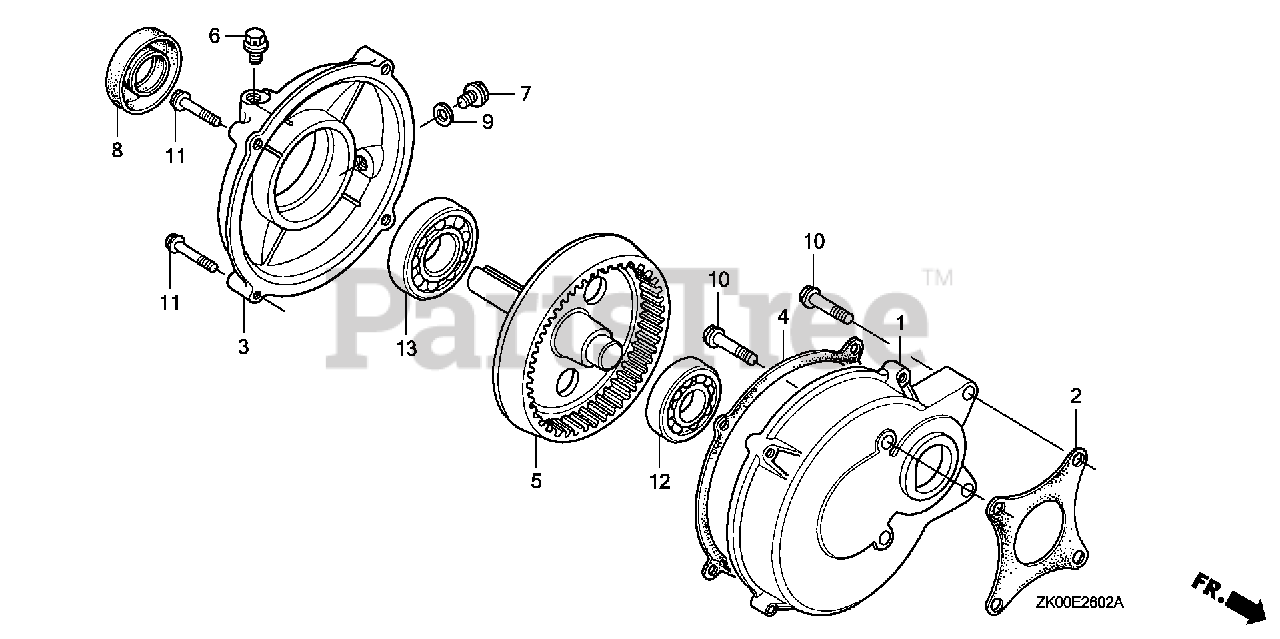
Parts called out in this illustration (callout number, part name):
1	CASE, REDUCTION
2	GASKET, REDUCTION CASE
3	COVER, REDUCTION
4	GASKET, REDUCTION COVER
5	SHAFT, P.T.O. (86T)
6	BOLT, BREATHING
7	BOLT, DRAIN PLUG (12X15)
8	OIL SEAL (25X41X6) (NOK)
9	WASHER, DRAIN PLUG (12MM)
10	BOLT, FLANGE (8X32)
11	BOLT, FLANGE (8X35)
12	BEARING, RADIAL BALL (6204)
13	BEARING, RADIAL BALL (6305)
